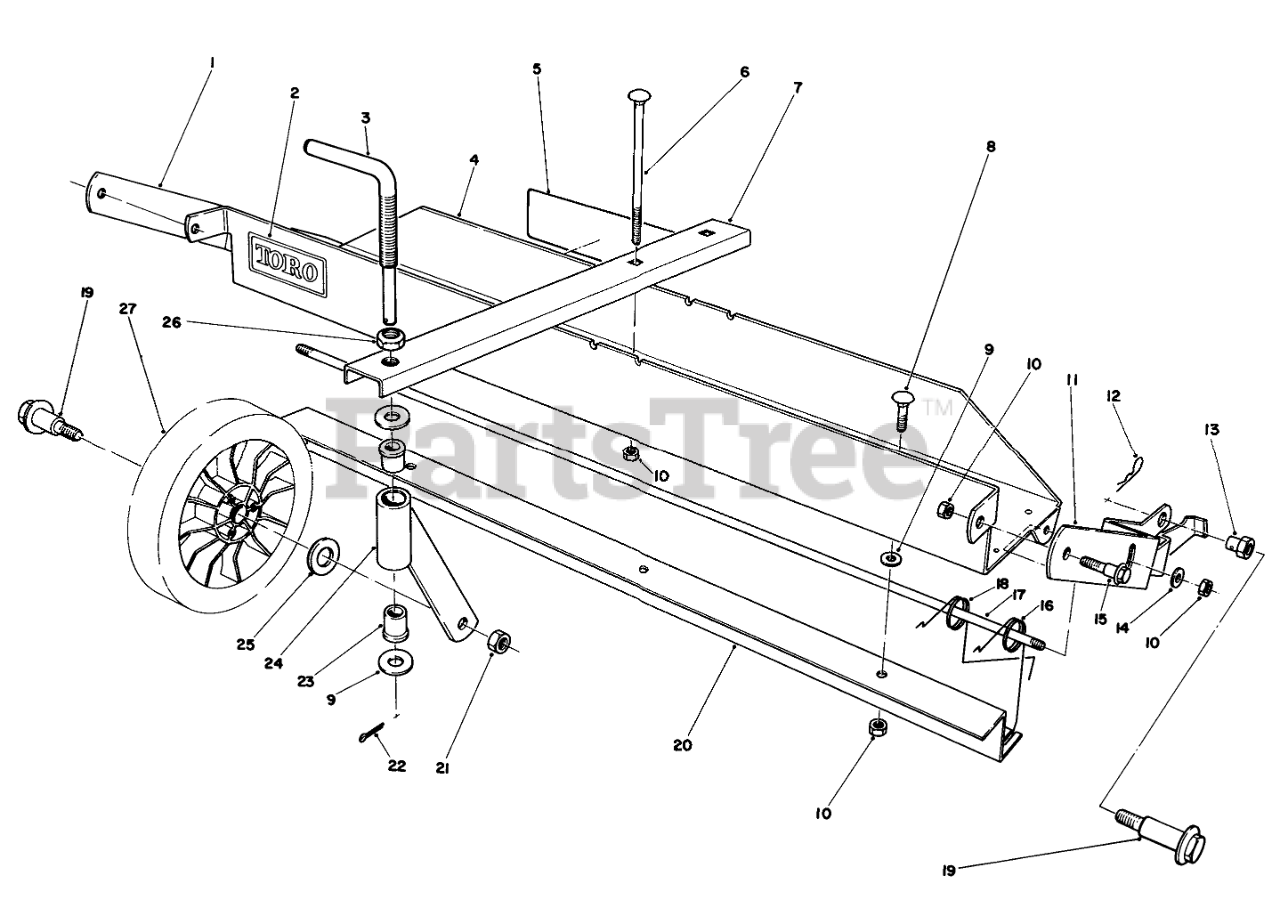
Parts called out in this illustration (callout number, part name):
1	Frame R.H.
2	Decal-Toro
3	CASTOR ADJ ROD
4	Frame-Main (Incl. Ref. #2)
5	Decal-Instruction
6	SCREW-CARR
7	Castor Frame
8	BOLT-CARR
9	WASHER-PLAIN
10	NUT-HEX, SIDE DEFORM
11	LH MTG FRAME
12	PIN-COTTER, HAIR
13	PIVOT NUT
14	WASHER-FLAT
15	BOLT-SHOULDER
16	DETHATCHER SPRING
17	SPRING SUPPORT ROD
18	DETHATCHER SPRING
19	BOLT-WHEEL
20	SPRING GUIDE STRAP
21	NUT-LOCK
22	PIN-COTTER
23	FLANGE BUSHING
24	Castor Tube & Support
25	WASHER
26	NUT-JAM
27	Wheel Assembly
